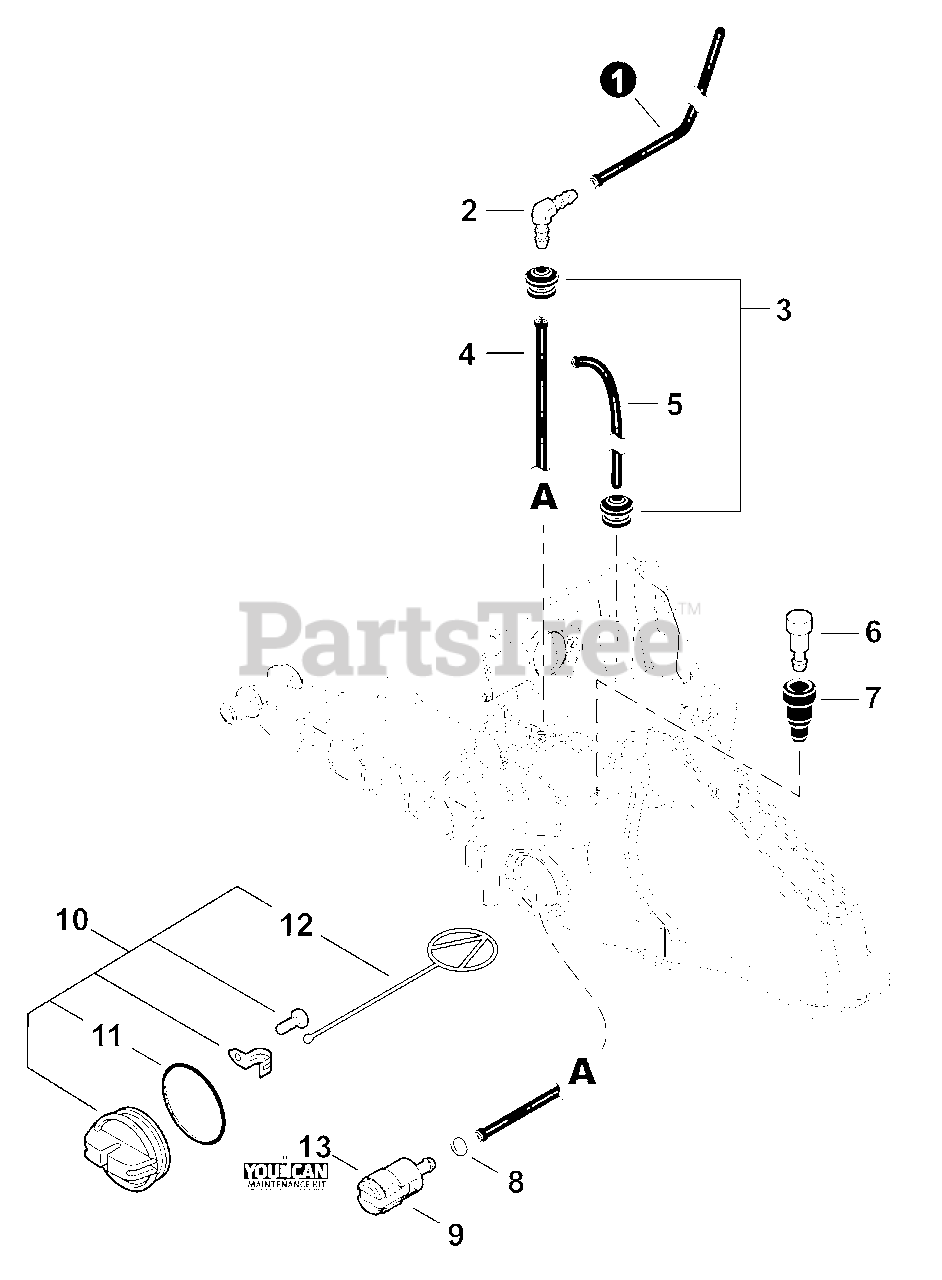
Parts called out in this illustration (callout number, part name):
1	PIPE, FUEL 3×6×135
2	CONNECTOR, PIPE
3	GROMMET
4	PIPE, FUEL 3×5×120 BLACK
5	PIPE, IMPULSE 3×6(8)×160
6	VENT ASSY
7	GROMMET, VENT
9	FILTER, FUEL
10	CAP ASSY, FUEL
11	O-RING 29
12	CONNECTOR, CAP L= 60 MM
13	TUNE-UP KIT - YOUCAN™
